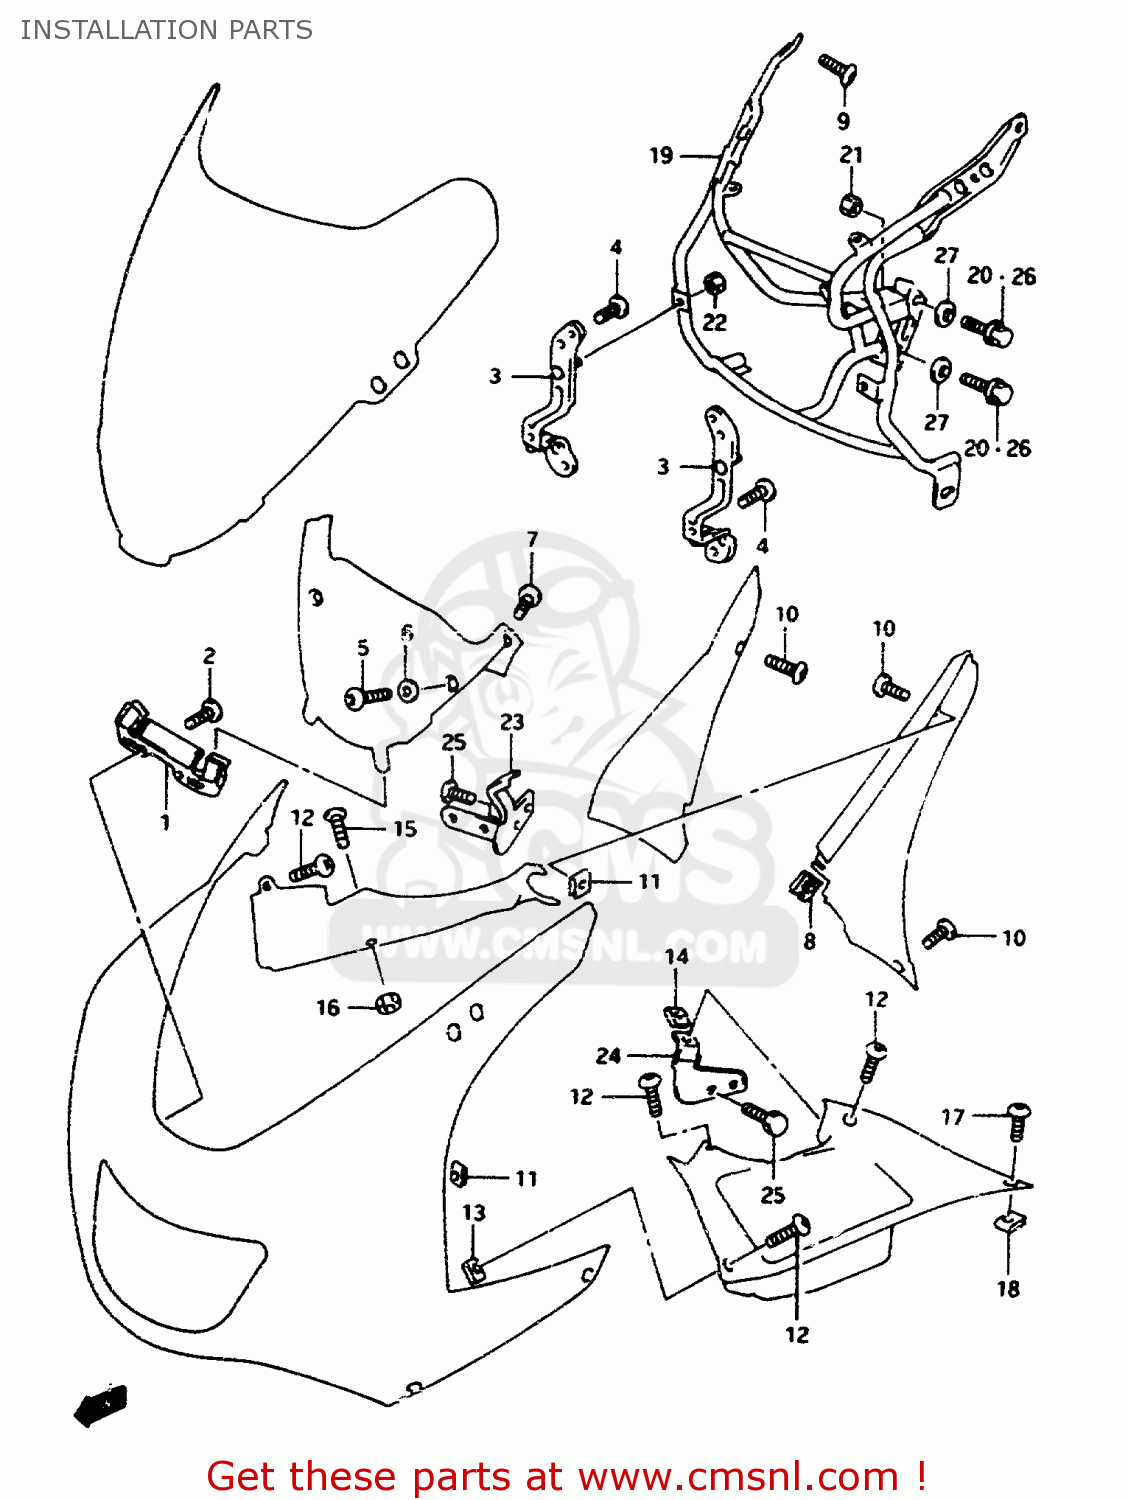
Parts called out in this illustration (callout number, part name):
1	BRACKET,WINDSCREEN FIT FR
2	SCREW 5X10
3	BRACKET,HEADLAMP FITING,R
4	SCREW 5X10
5	SCREW 5X12
6	WASHER(5.2X14X1.5)
7	SCREW
8	NUT
9	SCREW 5X10
10	SCREW
11	NUT
12	SCREW
13	NUT
14	NUT
15	SCREW
16	NUT
17	SCREW
18	NUT
19	BRACE,COWLING
20	BOLT(8X35)
21	NUT
22	NUT
23	BRACKET,SIDE PANEL,R
24	BRACKET,SIDE PANEL,L
25	BOLT
26	BOLT(8X40)
27	WASHER
